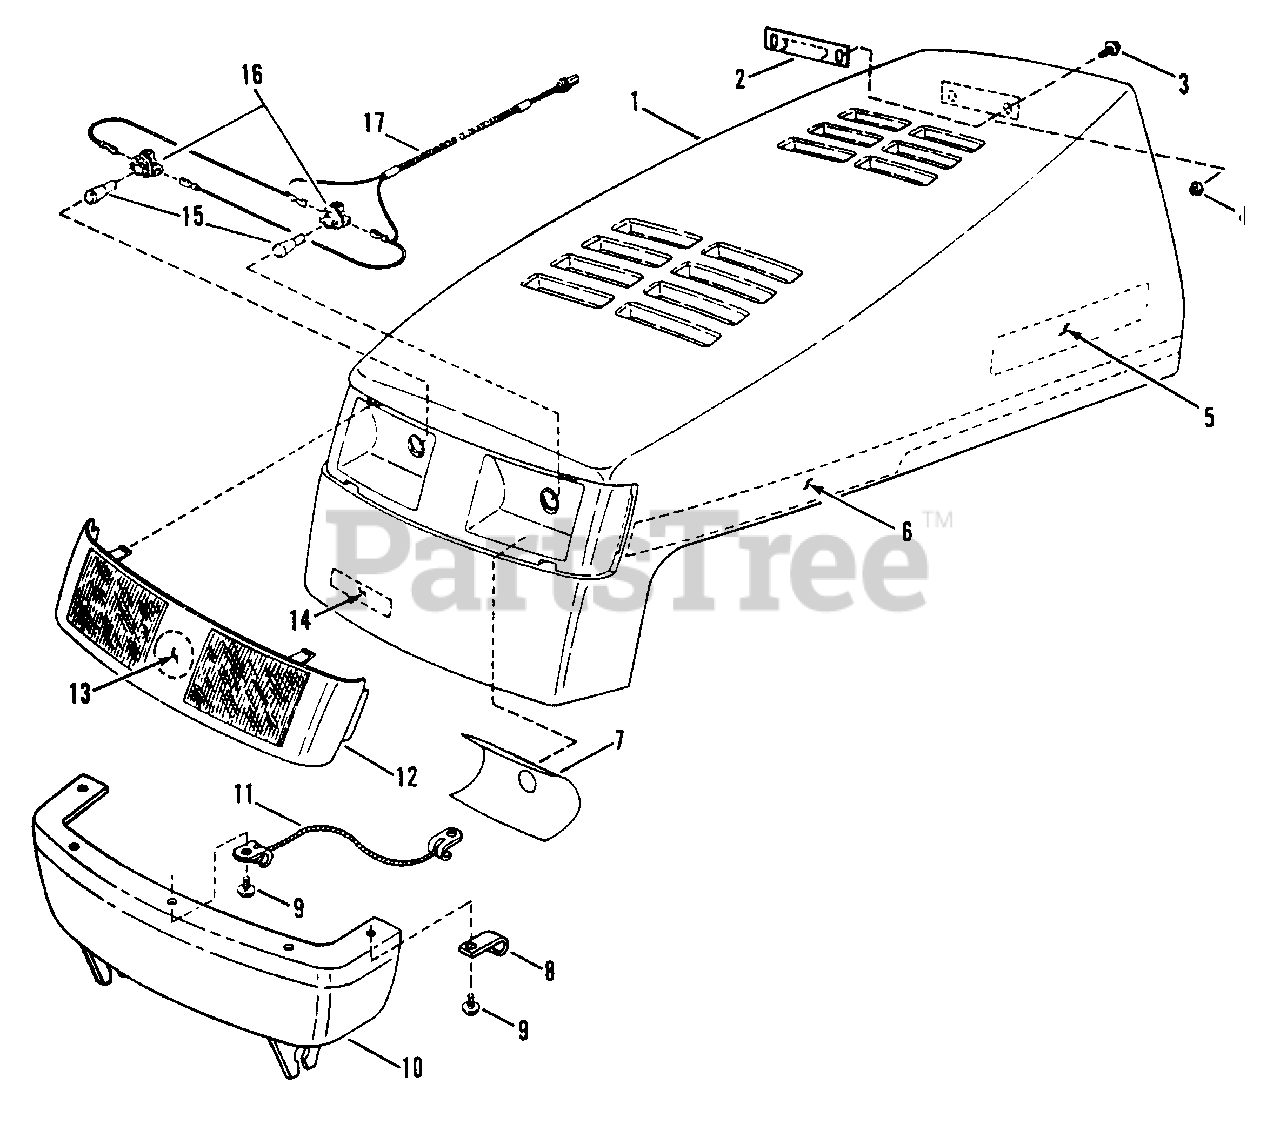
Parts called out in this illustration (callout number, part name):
1	HOOD
2	LATCH, Spring
3	SCREW, 1/4-20 x 5/8" Truss Head, Torx
4	NUT, 1/4-20 Hex Nyloc
5	DECAL-SNAPPER, 8" Molded Logo, White Letters
5	DECAL-SNAPPER, 8" Molded Logo, Silver Letters
6	DECAL, Hood, Right Side
6	DECAL, Hood, Left Side
7	DECAL, Lens, Left Side
8	CLIP "J"
9	SCREW, M4.8 x 1.59 x 16.00MM Special
10	SUPPORT, Hood
11	LANYARD, Hood
12	LENS, Solid Black
12	LENS, Clear
13	DECAL, Molded Medallion, Convertible Mower
14	DECAL, SNAPPER, 4" Molded Logo, White Letters
14	DECAL, SNAPPER, 4" Molded Logo, Teal Letters
15	BULB, Headlights
16	SOCKET, Headlight Bulb
17	HARNESS, Headlight Wiring
